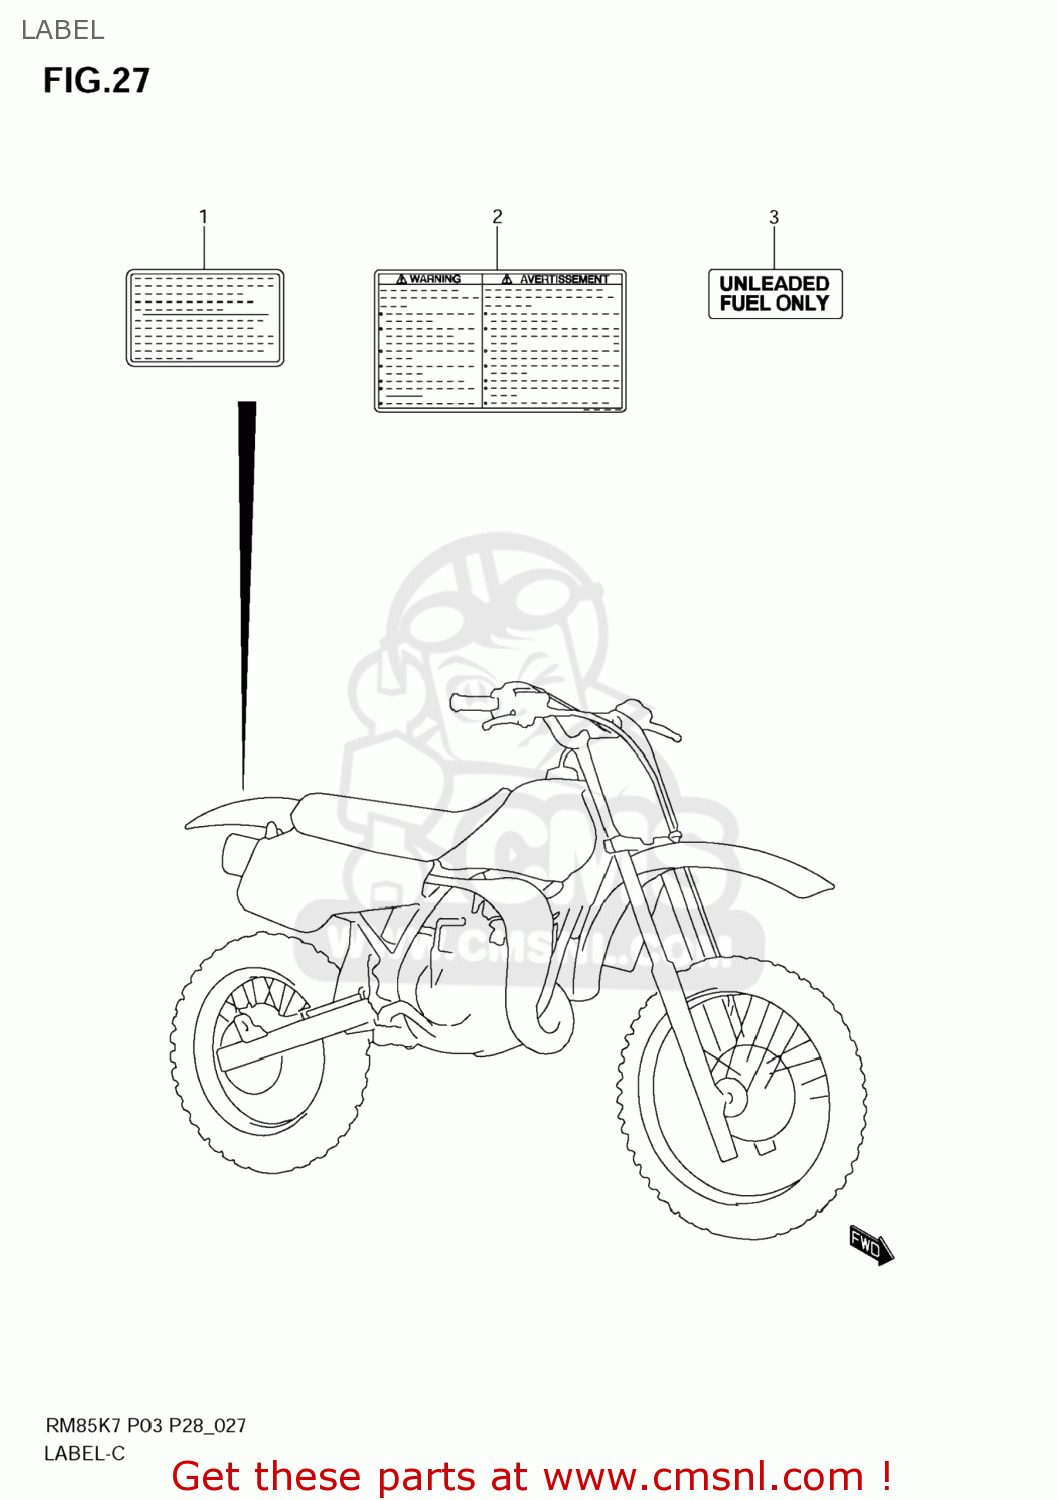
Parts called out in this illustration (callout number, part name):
1	LABEL,WARNING NO.2
2	LABEL,WARNING
3	LABEL,UNLEADED FUEL
4	MANUAL,OWNER'S
